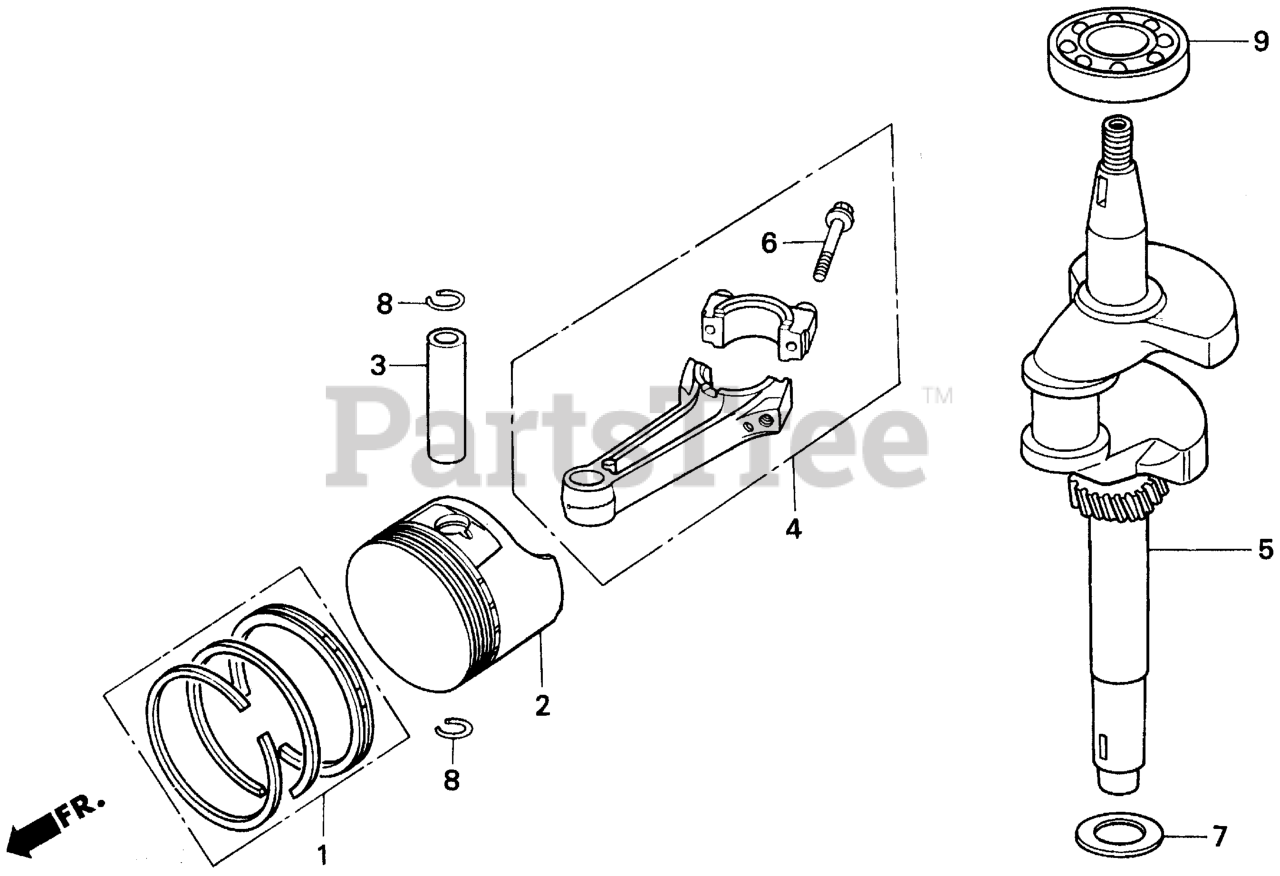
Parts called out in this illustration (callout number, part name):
1	RING SET, PISTON (STD) (GOETZE)
1	RING SET, PISTON (STD) (FEDERAL MOGUL)
1	RING SET, PISTON (STD) (NIPPON)
1	RING SET, PISTON (0.25) (FEDERAL MOGUL) Use from Engine SN 7666484.
1	RING SET, PISTON (OS 0.25) (NIPPON)
1	RING SET, PISTON (OS 0.25) (TEIKOKU) Use up to Engine SN 7666483.
1	RING SET, PISTON (0.50) (FEDERAL MOGUL) Use from Engine SN 7666484.
1	RING SET, PISTON (OS 0.50) (TEIKOKU)
1	RING SET, PISTON (0.75) (GOETZE) Use up to Engine SN 7666483.
1	RING SET, PISTON (OS 0.75) (FEDERAL MOGUL)
1	RING SET, PISTON (OS 0.75) (NIPPON)
2	PISTON (STD)
2	PISTON (OS 0.25) Use up to Engine SN 7666483.
2	PISTON (0.50)
2	PISTON (OS 0.75)
3	PIN, PISTON
4	ROD ASSY., CONNECTING (US 0.25) Use up to Engine SN 2250472.
4	ROD ASSY., CONNECTING
5	CRANKSHAFT
6	BOLT, CONNECTING ROD
7	WASHER C, THRUST (25MM)
8	CLIP, PISTON PIN (13MM)
9	BEARING, RADIAL BALL (62/22)
